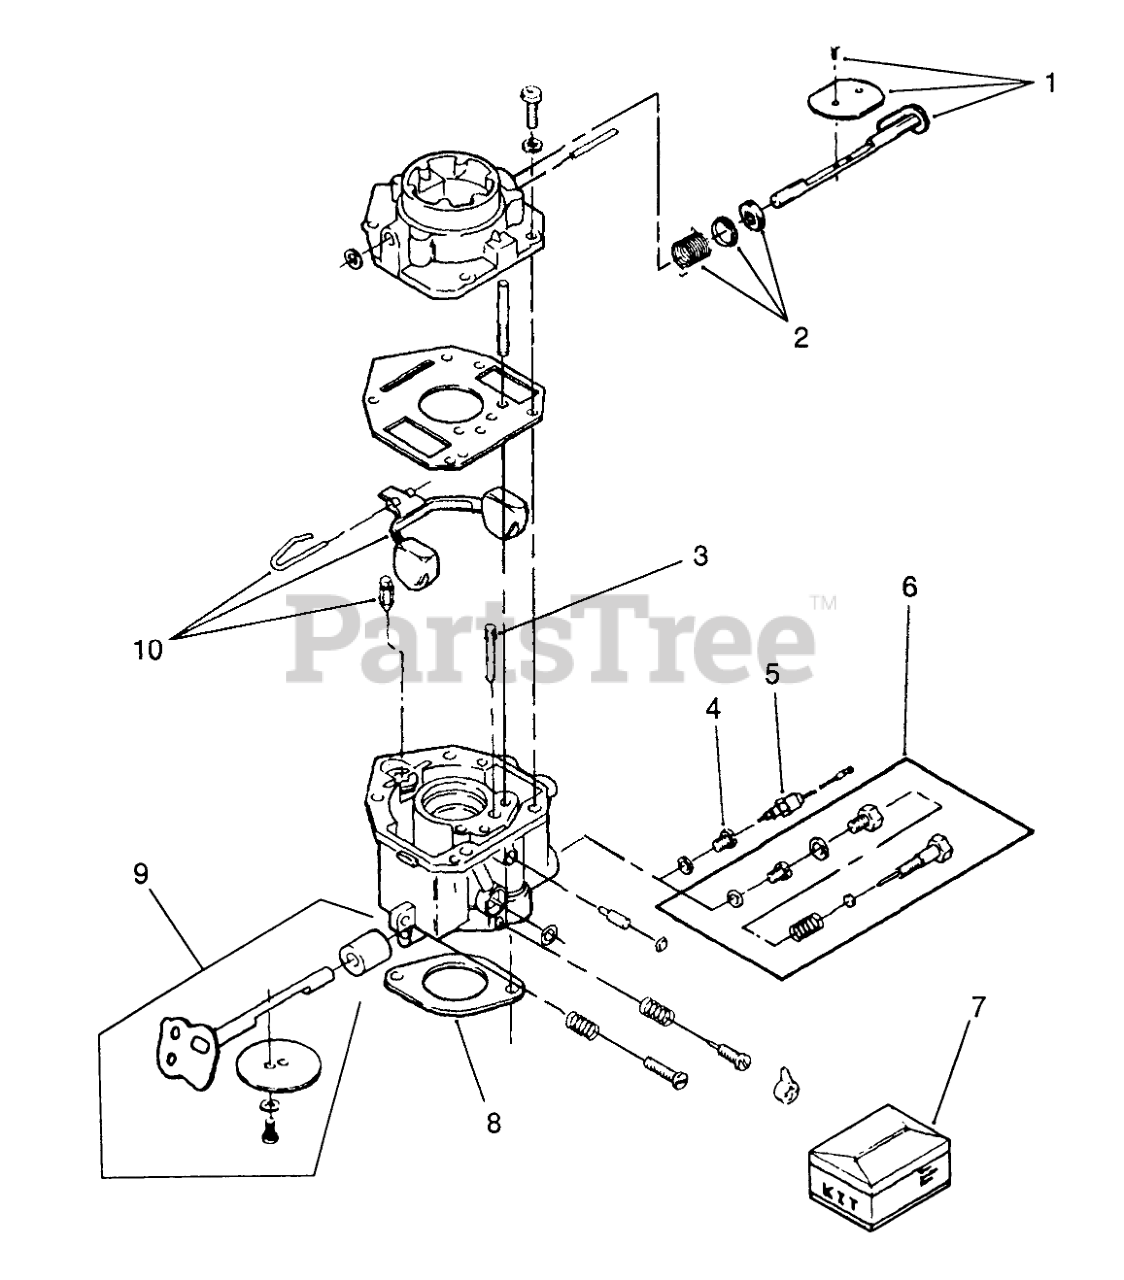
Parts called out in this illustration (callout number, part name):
1	Choke Shaft Kit
2	CHOKE-LEVER KIT
3	Idle Jet
4	POWER JET
5	Solenoid
6	FIXED-JET PKG
7	Carburetor Repair Kit
8	Gasket
9	SHAFT-THROTTLE KIT
10	Float Kit (Includes Float Pin)
